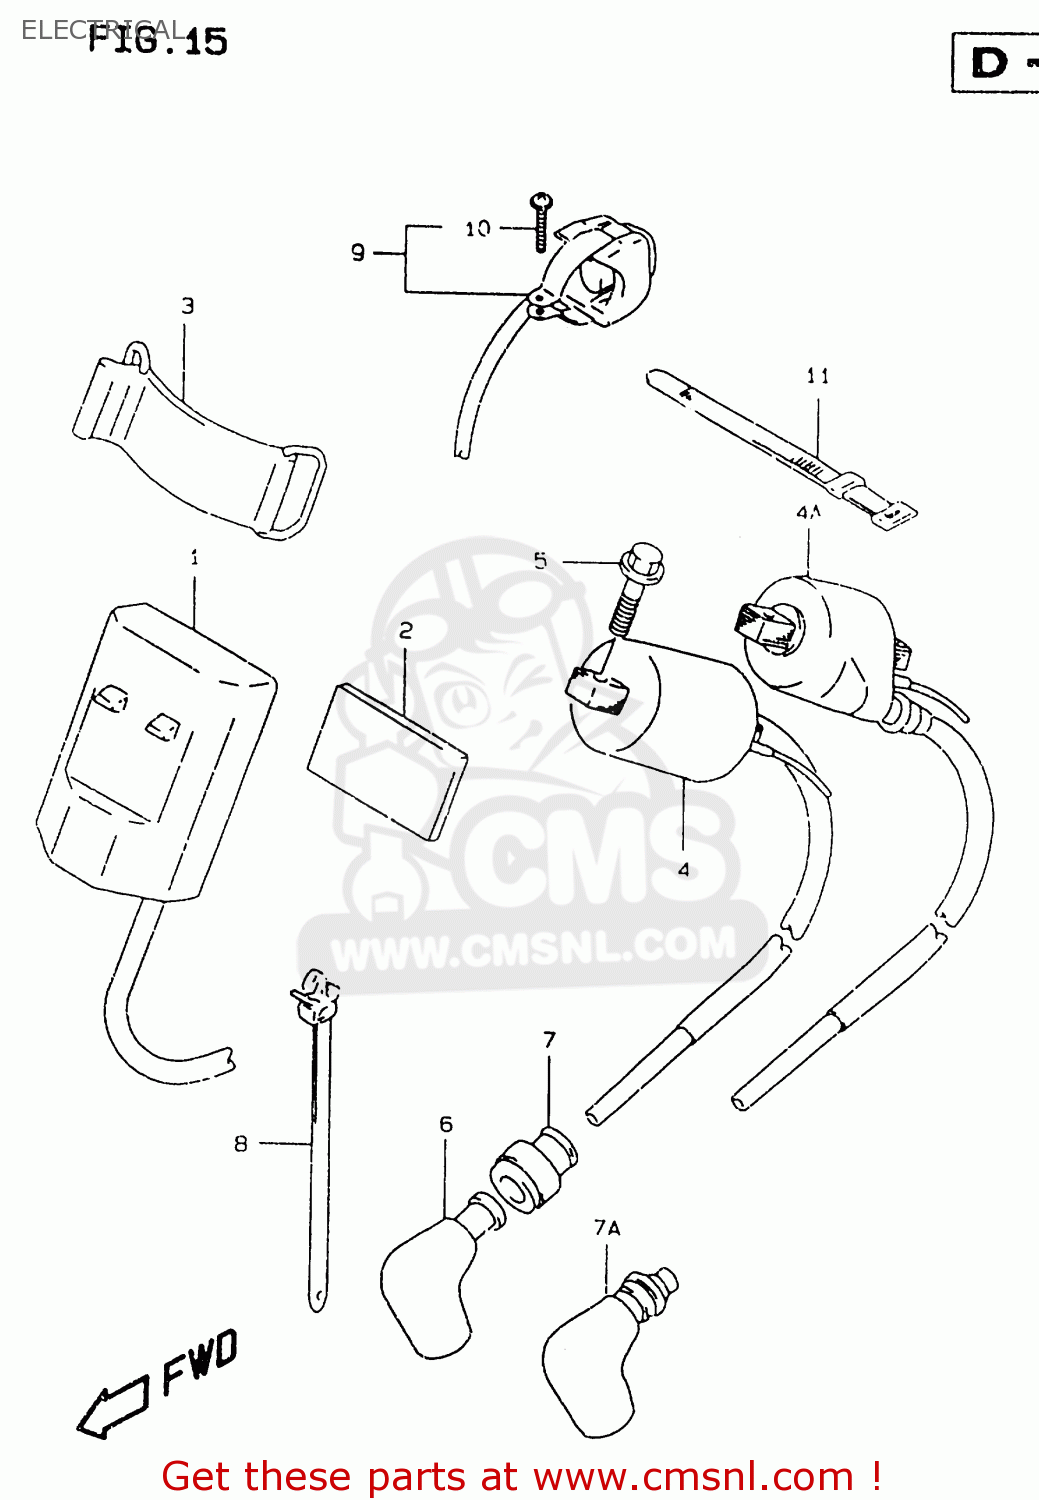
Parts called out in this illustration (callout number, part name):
1	CDI UNIT
2	PROTECTOR(170X95X3.0)
3	BAND,CDI UNIT(L:80)
4	COIL ASSY,IGNITION
4A	COIL ASSEMBLY,IGNITION
5	BOLT
6	CAP,SPARK PLUG
7	SEAL,HIGH TENSION CORD
7A	CAP,SPARK PLUG
8	CLAMP
9	SWITCH ASSY,ENGINE STOP
10	SCREW
11	CLAMP(L:120)
